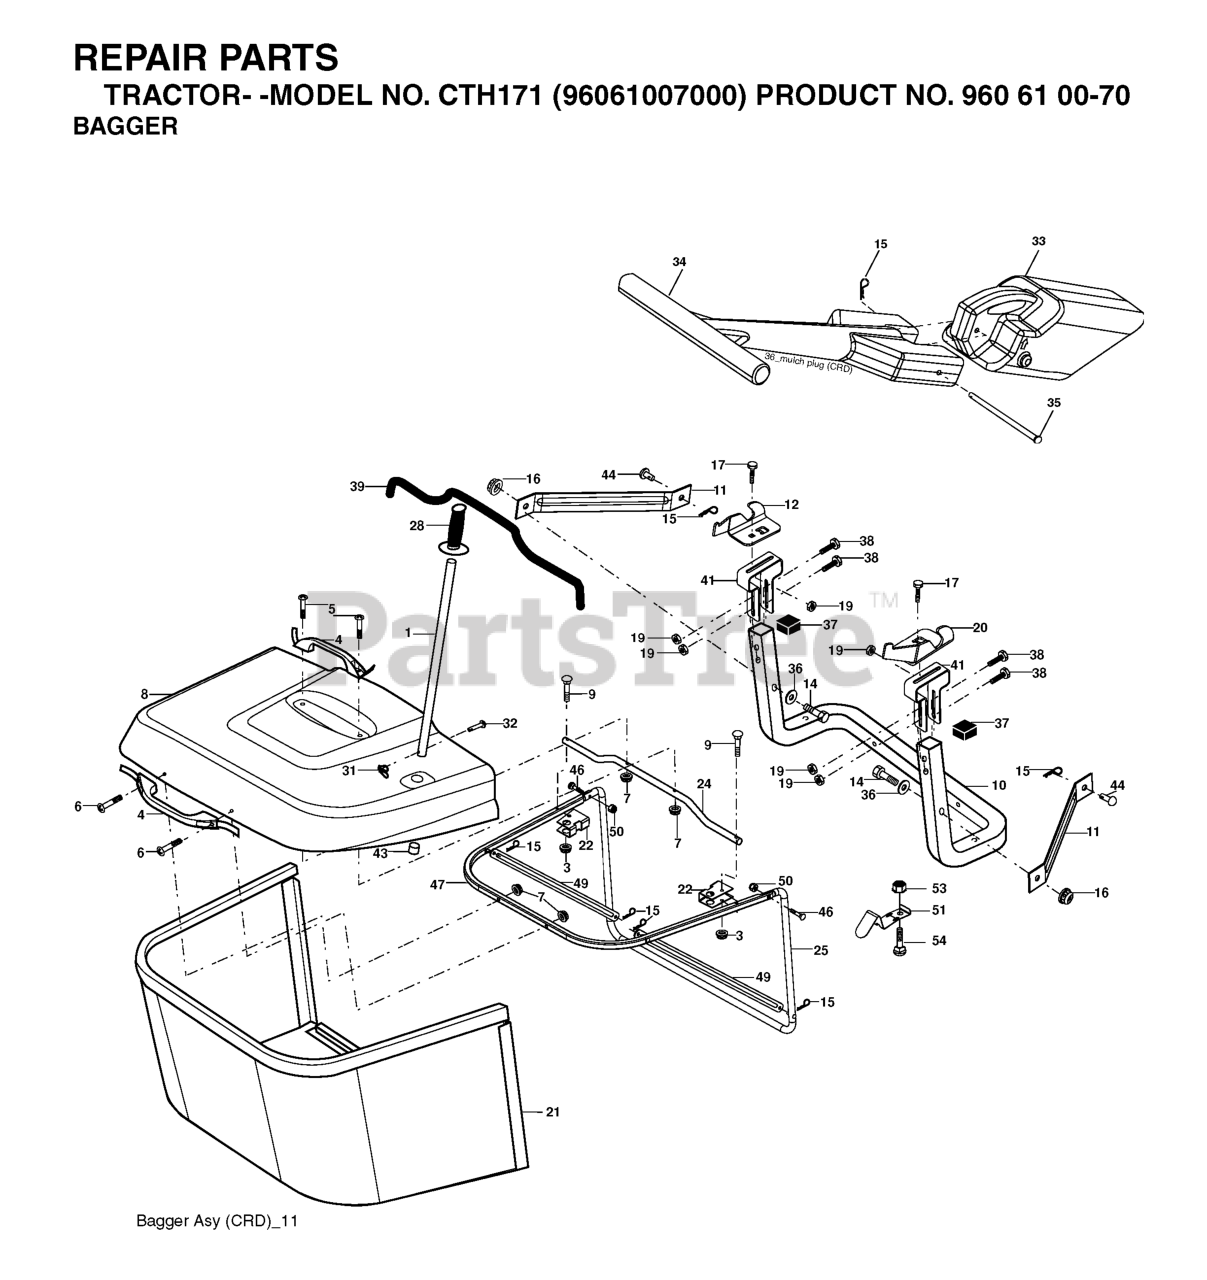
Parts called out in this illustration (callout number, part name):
1	TUBE HANDLE
3	NUT T
4	HANDLE.BAGGER.W/LVRS.BLK.CRD
5	SCREW.PAN.HEAD
6	REPL BY 532 75 00-29
8	COVER.PNT.BGR.CRD.WSLOTS.MS668
9	Bolt Carriage 1/4-20 x 2.25d x Gr.5
10	TUBE
11	BRACKET.SUPPORT.UPPER.BAG.CRD
12	BRKT PIVOT
14	BOLT-HEX EAK
15	RETAINER-SPRNG RB
16	NUT LOCK FLG 3/8-16 UNC
17	RP BOLT 5/16-18 X3/4 ZN/YEL GR
19	NUT LOCK HEX FLANGE 5/16-18
20	BRKT.PIVOT.RH.CRD
22	BRKT.SIDE.BAG.CRD
24	TUBE.PIVOT.BAG.CRD.BLACK
25	PIPE
28	GRIP.HANDLE.BLACK
31	RETAINER CLIP
32	RIVET,DRILLED
33	PLUG.MULCHER.92 CRD
34	HANDLE.MULCHER.92.CRD (2 2)
36	WASHER
37	Plug Support Bagger CRD
38	BOLT.5/16-18X2.5
39	SEAL.TRIM.37'
41	BRKT.VERT.ADJ.BAGGER.CRD
43	PLUG, TUBING END
47	PIPE
49	ROD
51	LATCH
53	NUT
54	BOLT
